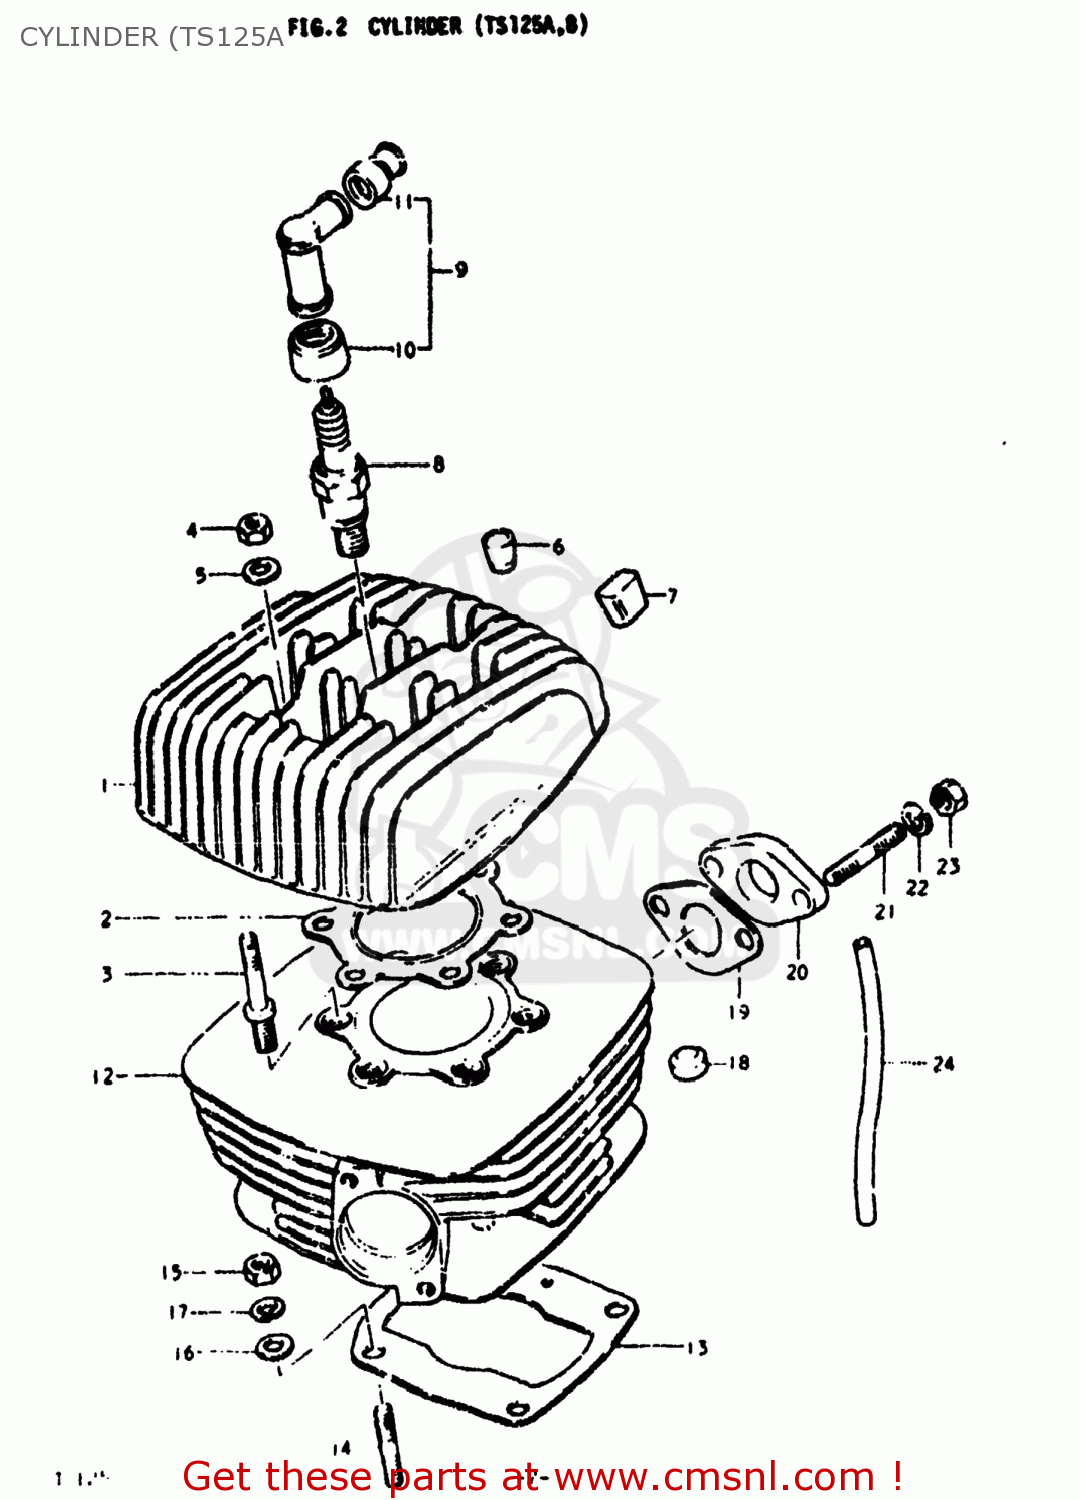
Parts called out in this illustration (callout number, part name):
1	HEAD,CYLINDER
2	GASKET,CYLINDER HEAD (MCA)
3	BOLT,STUD
4	NUT (8MM)
5	WASHER
6	PAD,CYLINDER HEAD
7	PAD,CYLINDER
8	SPARK PLUG
9	CAP,SPARK PLUG
10	SEAL,SPARK PLUG
11	SEAL,SPARK PLU
12	CYLINDER
13	GASKET,CYLINDER (MCA)
14	STUD 8X25
15	NUT
16	WASHER
17	LOCK WASHER
18	PAD,CYLINDER
19	GASKET,CARB (MCA)
20	INSULATOR,CARBURETOR
21	STUD BOLT
22	LOCK WASHER
23	NUT
24	HOSE
